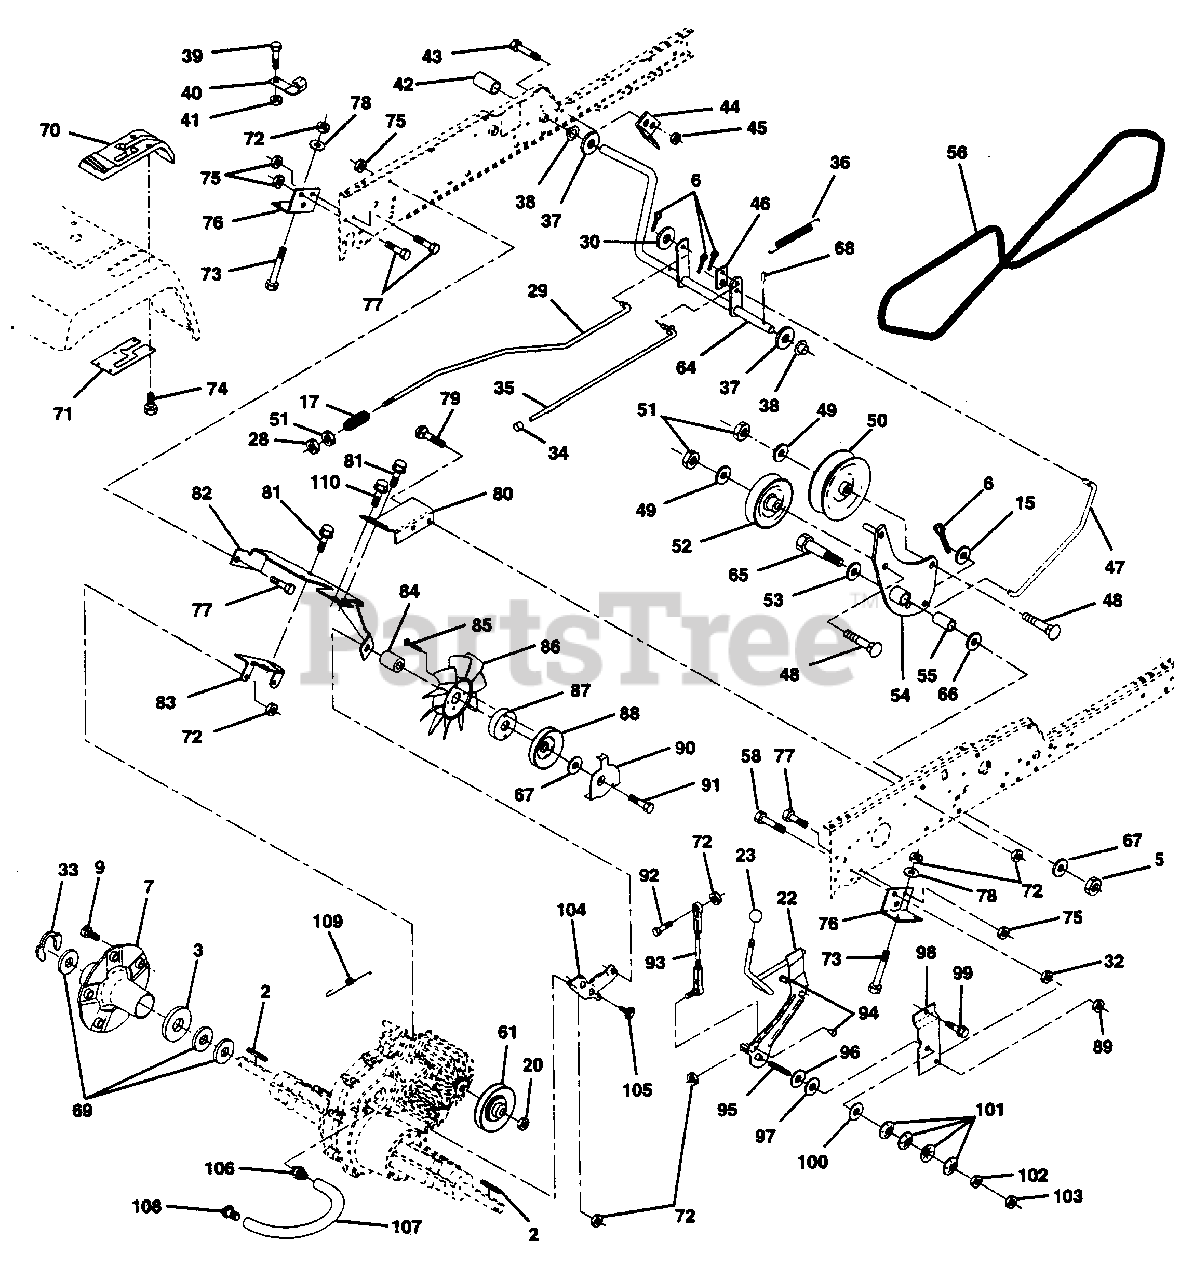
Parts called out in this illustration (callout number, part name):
2	Key 1/4 x 2.5
3	Washer Thrust Axle Harden
5	Nut Crownlock 3/8-16
6	Pin Cotter 1/8 x 3/4
7	Wheel Hub Asm.
15	Washer 13/32 x 13/16 x 16 Ga.
17	Spring Rod Brake
20	Nut Hex Jam Toplock 1/2-20
22	Shaft Arm Asm
28	Nut, Hex Jam 3/8-16
30	Washer 13/32 x 1 x 14Ga
31	Pin Cotter 3/32 x 3/4
32	Nut Hex 7/16-14
35	Rod Parking Brake
36	Spring Extension
37	Washer 25/32 x 1-1/4 x 16 Ga.
38	Nyliner
39	Screw Fin #10-24 x 1
40	Actuator Interlock Switch
41	Nut Lock #10-24
43	Bolt Hex Head 1/4-20 x 3/4
44	Bracket Interlock
45	Nut Lock W/Insert 1/4-20
46	Retainer Spring
48	Bolt Carriage 3/8-16 x 1-3/4 Gr. 5
49	Washer 13/32 x 7/8 x 13 Ga
50	Pulley Idler Flat
51	Nut, Crownlock 3/8-16
52	Pulley Idler Grooved
53	Washer Hartdened
54	Clutch Arm Asm
55	Bearing, Idler
58	Bolt Fin Hex 7/16-14 x 1-1/2
61	Pullery Transaxle
64	Shaft Asm Brake Parking Clutch
65	Bolt Shoulder
66	Washer Hardened
67	Washer 13/32 x 13/16 x 12 Ga
70	Console Hydro Fender
71	Plate Console Shift
72	Locknut Hex W/Washer Insert
73	Bolt Fin Hex 5/16-18 x 3
74	Screw, Hex Wsh Hi-Lo 1/4-1/2
75	Nut Lock Hex 7/16
76	Bracket Transaxle
77	Bolt Fin Hex 7/16-14 x 1
78	Washer 11/32 x 3/4 x 12 Ga.
79	Bolt Carriage 5/16-18 x 5/8
80	Bracket Torque RH
81	Screw Thdrol 3/8-16 x 3/4
82	Bracket Mount Torque/Fan
83	Strap Torque Mid
85	Screw #10-24 x 1-1/4
88	Pulley Idler
89	Nut, Crownlock 7/16-14
91	Screw Thdrol 3/8-16 x 2-3/4
92	Bolt Fin Hex 5/16-18 x 1.75
93	Link Shift Asm
94	Fastner Christmas Tree
95	Screw Set 5/16-18 x 1.75
96	Washer Nickel Plated
97	Bearing Trust
98	Bracket Shift
99	Screw Thdrol 3/8-16 x 1-1/2
100	Washer Compression
101	Washer Bellville
102	Nut Hex Nylok
103	Nut Hex Jam 5/16-18
104	Bracket Idler
105	Screw Tap 1/4-20 x 1/2
106	Fitting Vent Hose
109	Spring Return Brake
